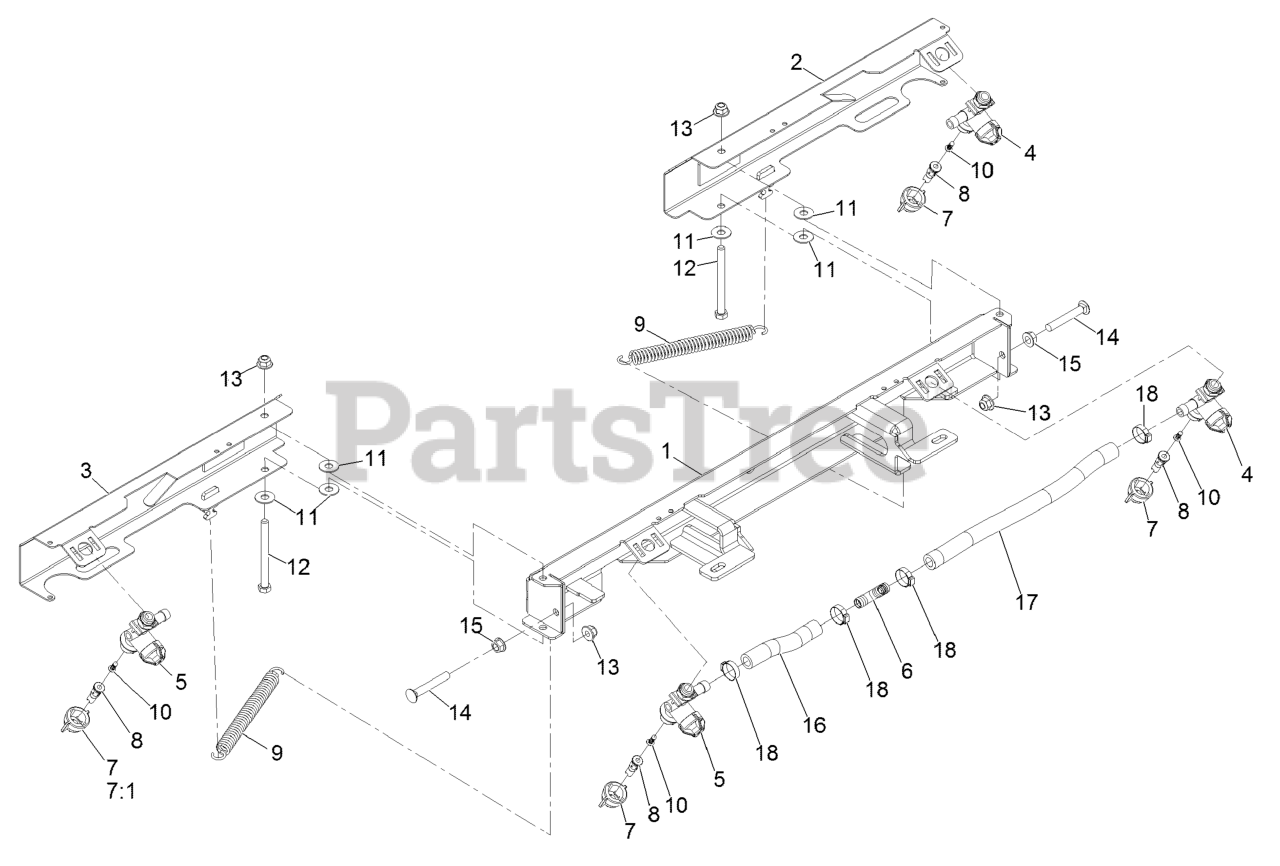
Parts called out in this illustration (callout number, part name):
1	BOOM-CENTER
2	BOOM-WING, RT
3	BOOM-WING, LT
4	BODY-NOZZLE, RIGHT
5	BODY-NOZZLE, LEFT
6	FITTING-TEE, BARB
7	CAP-NOZZLE
7:1	SEAT-GASKET
8	TIP-SPRAY, 025
9	SPRING-EXTENSION
10	STRAINER-NOZZLE, 50M 5PSI
11	WASHER-FLAT
12	SCREW-HH
13	Nut-Hex Flange
14	SCREW-CARR
15	Nut-Hex Flange
16	Hose-Spray
17	Hose-Spray
18	CLAMP-OETIKER, 167
